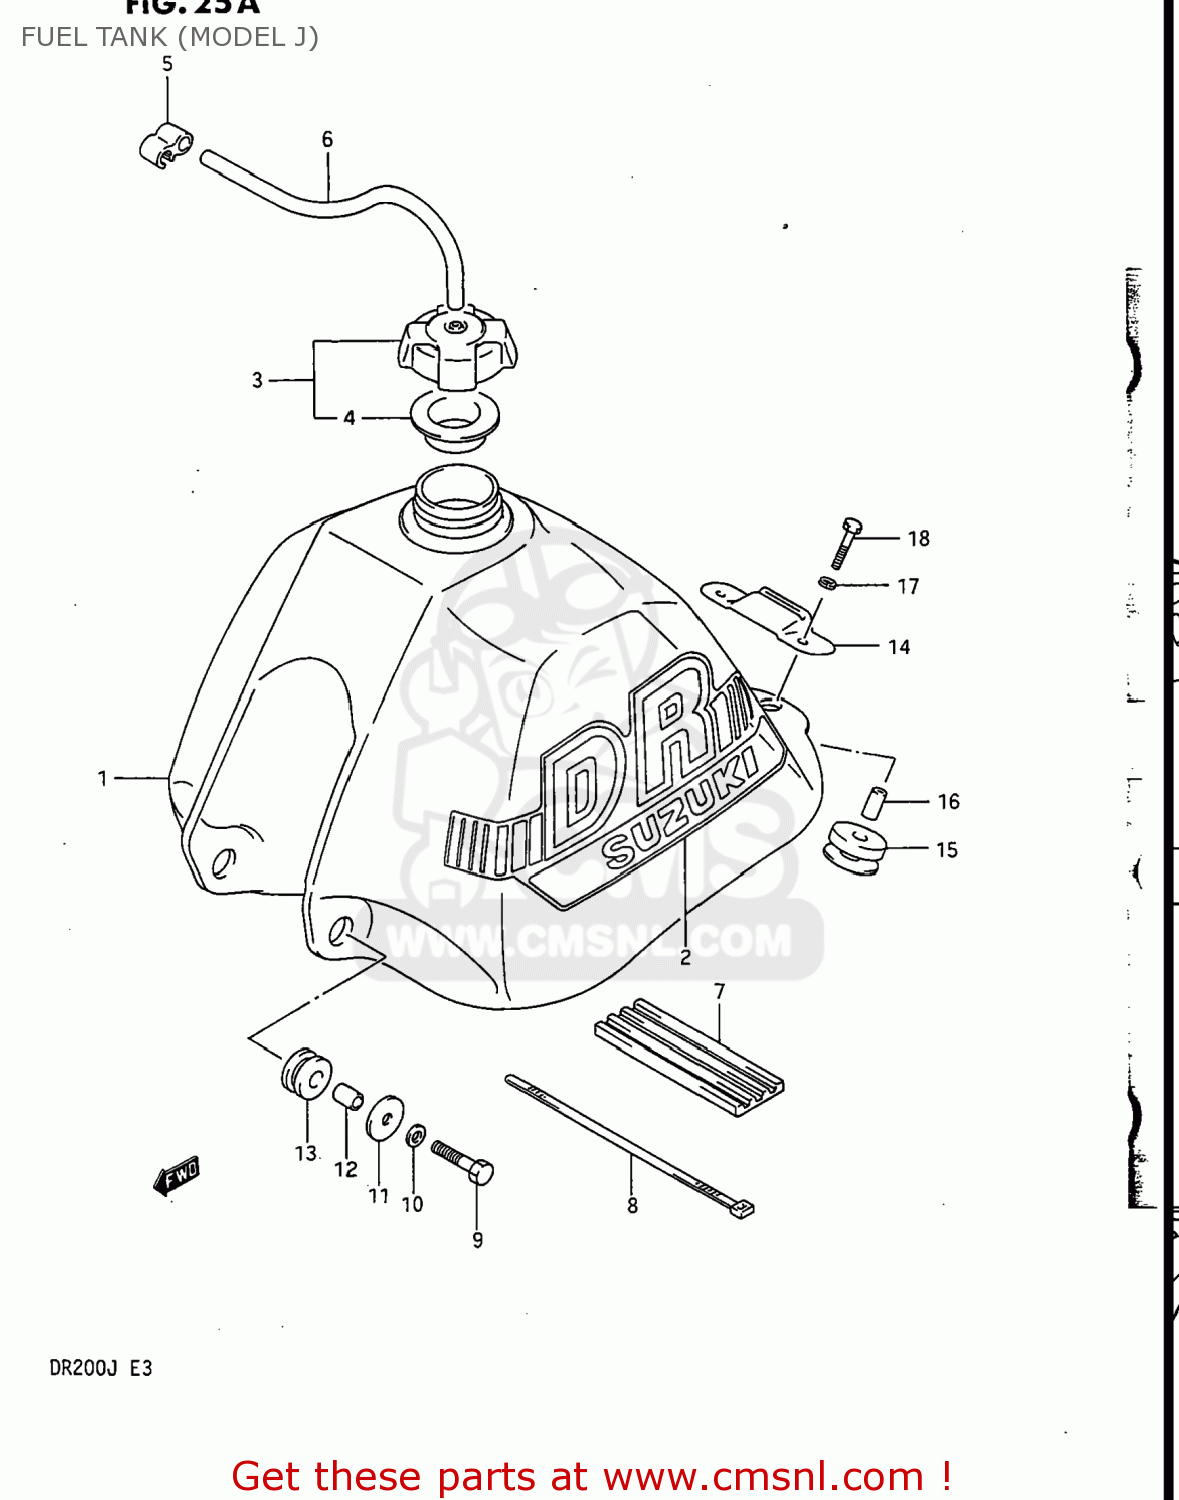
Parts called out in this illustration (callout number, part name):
1	TANK ASSEMBLY,FUEL
2	TAPE SET,FUEL TANK STRIPE
3	CAP SET,FUEL TANK
4	GASKET,FUEL TANK CAP (NAS)
5	CLAMP,FUEL TANK BREATHER HOSE
6	HOSE
7	CUSHION,FUEL TANK UPR FR
8	CLAMP
9	BOLT
10	LOCK WASHER
11	WASHER (8.5X29X1.6)
12	SPACER (8.8X12X13.5)
13	CUSHION
14	PLATE,SEAT FR HOOK
15	CUSHION
16	SPACER
17	WASHER,LOCK
18	BOLT
